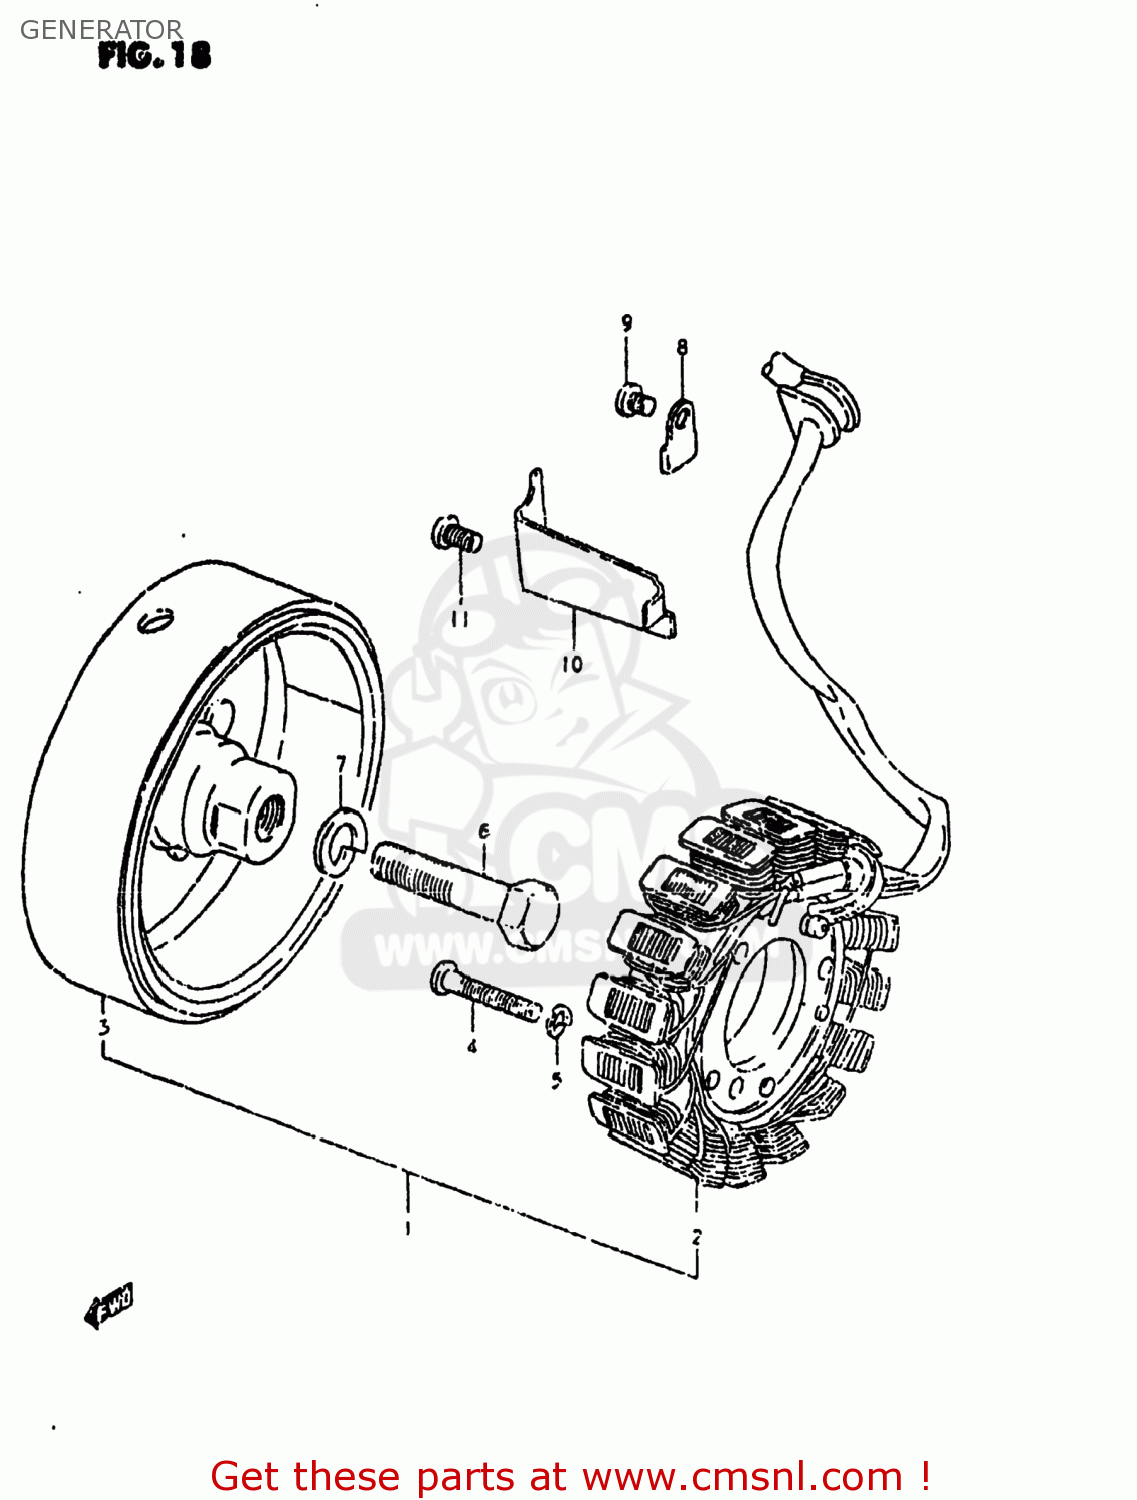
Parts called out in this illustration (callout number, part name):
1	GENERATOR ASSEMBLY
2	STATOR ASSEMBLY
3	ROTOR ASSEMBLY
4	SCREW
5	LOCK WASHER
6	BOLT 12X45
7	WASHER,LOCK 12
8	CLAMP,GENERATOR LEAD WIRE
9	SCREW
10	CLAMP,GENERATOR LEAD WIRE
11	SCREW
